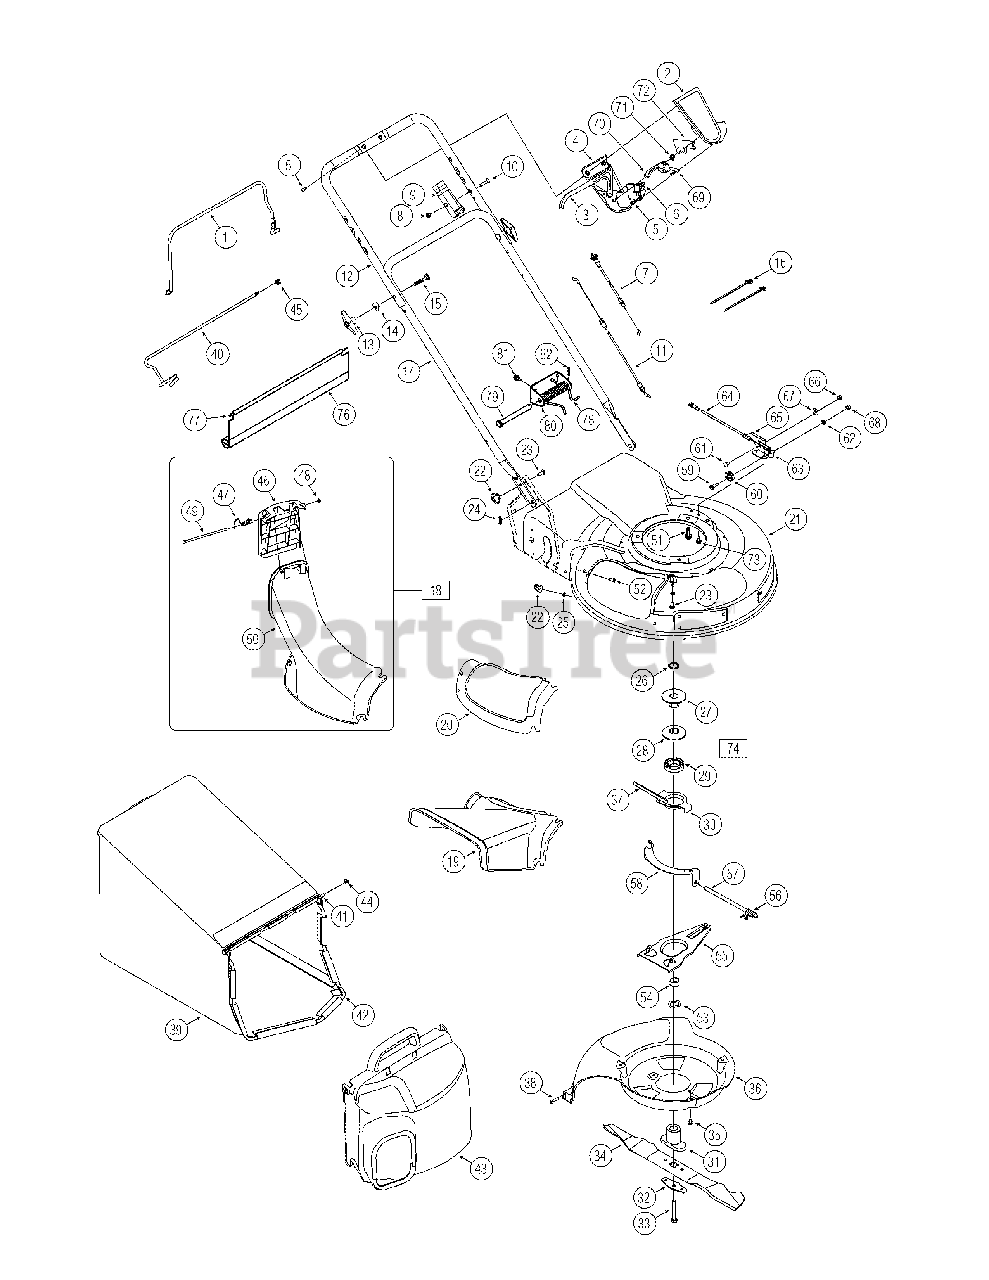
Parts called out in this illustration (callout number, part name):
1	Blade Control
2	Upper Control Housing
3	Drive Control
4	Lower Control Housing
5	C Sunk Tap Screw, #10 X.75 Lg
6	Cable Mounting Cap
7	Drive Cable - 51"
8	Top Lock Nut, 1/4-20
9	Control Housing
10	Oval C-Sunk Screw
11	Control Cable - 47"
12	Upper Handle
13	Wing Nut
14	Sdle Washer, .320 ID x.830 OD
15	Carriage Bolt, 5/16-18 x 2.0
16	Cable Tie
18	Adapter Assembly
19	Side Discharge Chute
20	Mulch Cover
23	Carriage Bolt, 1/4-20 x .75
24	Cotter Pin
25	Push Nut, .25 x ID x .50 OD
26	Sleeve Spacer, .88ID x 1.13 OD
27	Half Pulley: 2.62 OD
28	Half Pulley: 2.62 OD x 1.61
29	Ball Bearing
31	Blade Adapter
32	Blade Bell Support
33	Hex Bolt, 3/8-24 x 2.5
34	21" Mulching Blade
35	Screw, 1/4-20 x 3.75
37	Belt, 3/8 x 39.24
38	HL Screw, #12-16 x 1.00
39	Grass Catcher
40	Support Rod w/ Rope
41	Pivot Rod
42	Grass Catcher Frame
43	Grass Catcher Cover
44	Cap Nut
45	Hex Nut 5/16-18
46	Chute Door
47	Torsion Spring
48	Push Cap
49	Pivot Rod
50	Grass Catcher Adapter
51	Sems Screw, 3/8-16 x 1.00
52	Carriage Screw, 1/4-20 x.62
53	Wave Washer, 1.38 ID x..88 OD
54	Slve Spacer, .88 ID x 1.00 OD
57	Pivot Shaft
59	Shlder Screw, .375 ID x X 1/4-14
60	Cable Roller
61	Carriage Screw, 1/4-20 x.50
62	Lock Washer, 1/4
63	Cable Mounting Bracket
64	6 Speed Cable
65	Cable Adjustment Bracket
66	Hex Nut 1/4-20
67	Bell Washer.265 ID x.75 OD
68	Hex Nut 1/4-28
69	Shift Lever Spring
70	6 Speed Shift Lever
71	Gear Insert
72	6 Spd. Rack Cable Bracket
73	Screw, 1/4-20 x .625
74	Pulley Assembly
76	Trail Shield
77	Trail Shield Wire
78	Torsion Spring
79	Clevis Pin .50 Dia x 4.82 Lg
80	Height Adjustment Spring Brkt
81	Screw 1/4-14 x .825
82	Cotter Pin
